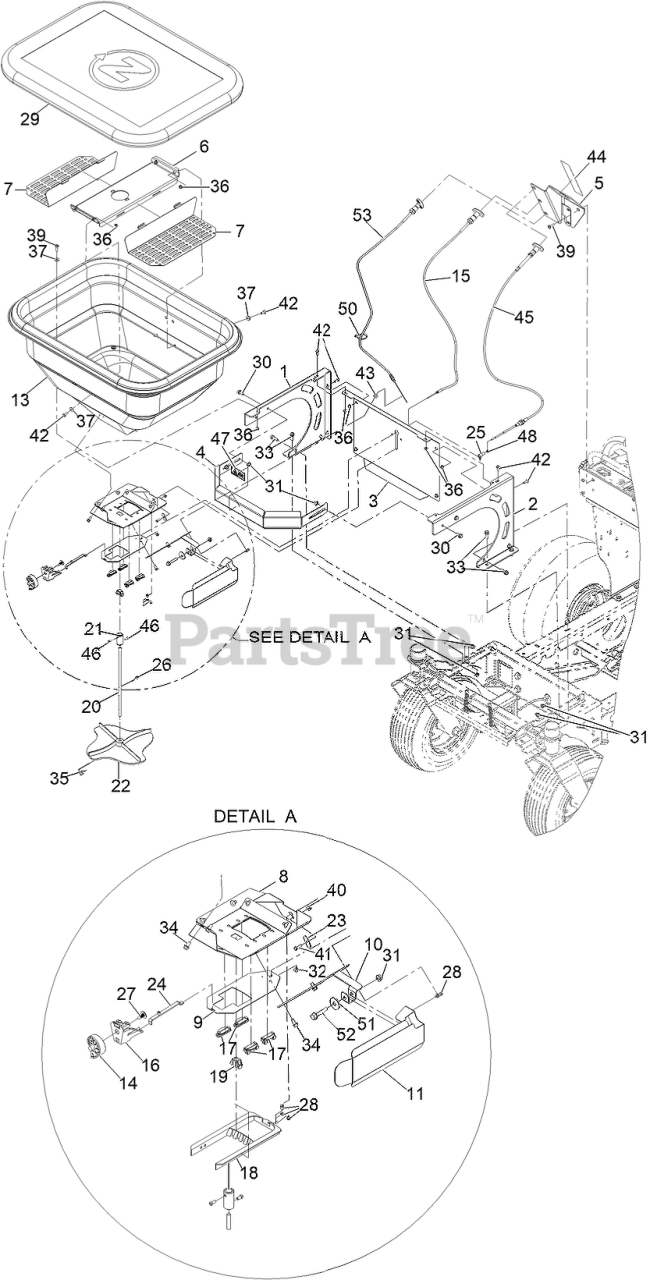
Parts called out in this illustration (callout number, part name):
1	Side-Hopper, Rt
2	Side-Hopper, Lt
3	Backshield-Hopper
4	BUMPER-FRONT, HOPPER
5	Mount-Speedometer
6	PAN-HOPPER, 220
7	SCREEN-HOPPER, 220
8	BASE PLATE, HOPPER, 220
9	Slide-Door, Hopper
10	MOUNT-DEFLECTOR, SIDE
11	Deflector-Side, Spreader
13	ASY-HOPPER 220 LB
15	CABLE-PUSH/PULL
16	MOUNT-DIAL
17	GUIDE-RATE, GATE
18	DIFFUSER
19	HOPPER BOTTOM BEARING
20	SHAFT-HOPPER, 220
21	COUPLER-SS
22	Spinner-Spreader
23	RETAINER, CABLE
24	RATE GATE LINK ASM
25	BALL JOINT-SS
26	WIRE-AGITATOR
27	Footpad Fastener
28	WIRE-STOP
29	COVER-HOPPER, LARGE
30	SCREW-HHF
31	Nut-Hex Flange
32	Nut,NYL Lock,#10-32,ST/ST 18-8
33	SCREW-HHF
34	SCREW-HHF
35	Clip-Spinner
36	Nut-Hex Flange
39	Screw-Hsbhf
40	Nut-Hex Flange
41	SCREW-HH
42	Screw-Hsbhf
43	Grommet-Rubber
44	Decal-Hopper Control
45	CABLE-PUSH/PULL
46	Screw-SQH
47	Decal-Dismemberment Hazard
48	Nut,Hex Jam Mch Scr,10-32,Sst
51	WASHER
52	Screw-HHF
53	Cable-Control, Turn Lock 2.00 Trvl
